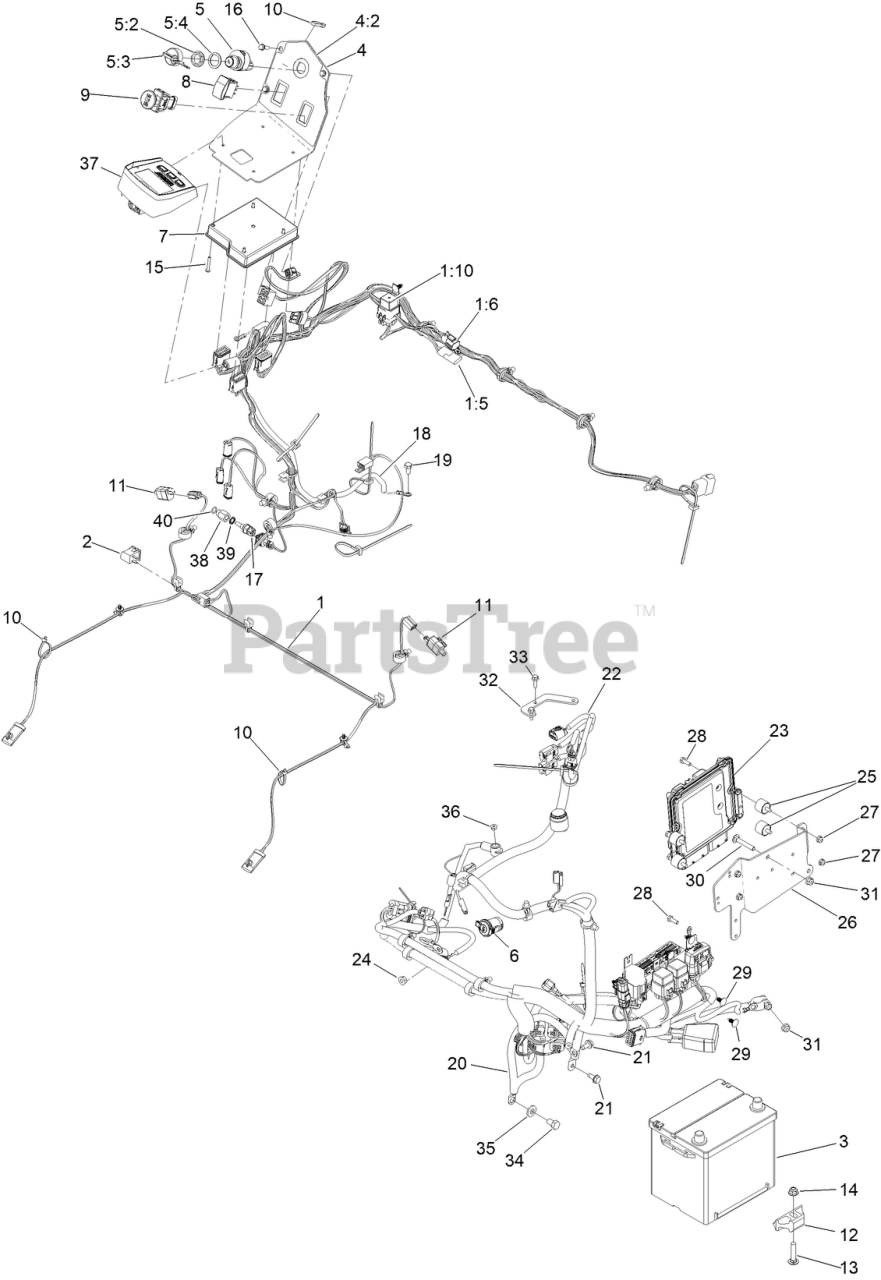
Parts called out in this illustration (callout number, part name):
1	HARNESS-WIRE, MAIN
1:5	CAP-PLUG
1:6	CAP-PLUG, 6 WAY
1:10	RELAY-MINI
2	SWITCH-BAIL
3	BATTERY-DRY
4	CONSOLE ASM
4:2	DECAL-CONSOLE
5	IGNITION SWITCH ASM
5:2	NUT-MOUNTING
5:3	IGNITION KEY SET
5:4	WASHER-BACKUP
6	PORT-POWER, 12V
7	MODULE-MCU
8	SWITCH
9	SWITCH-PTO, SEALED
10	TIE-CABLE
11	SWITCH
12	RETAINER-BATTERY
13	SCREW-CARR
14	NUT-HF, NI
15	SCREW-PPH
16	SCREW-HWH
17	SENSOR-TEMPERATURE
18	HARNESS-WIRE, JUMPER
19	BOLT
20	CABLE-BATTERY
21	SCREW-HWHTF
22	HARNESS-WIRE, YANMAR
23	CONTROLLER-ENGINE
24	NUT-HF
25	MOUNT-CYLINDRICAL
26	MOUNT-CONTROL UNIT, ENGINE
27	NUT-HF
28	SCREW-HH
29	PLUG-PLASTIC
30	BOLT-CARR
31	NUT-HF, NI
32	BRACKET-WIRING, ENGINE
33	SCREW-HHF
34	SCREW-HH
35	WASHER-BELLEVILLE
36	NUT-HF
37	MODULE-HORIZON
38	FITTING-STR, 6MORB-M12, STL, CZ
39	WASHER-SEAL, M12
40	O-RING
